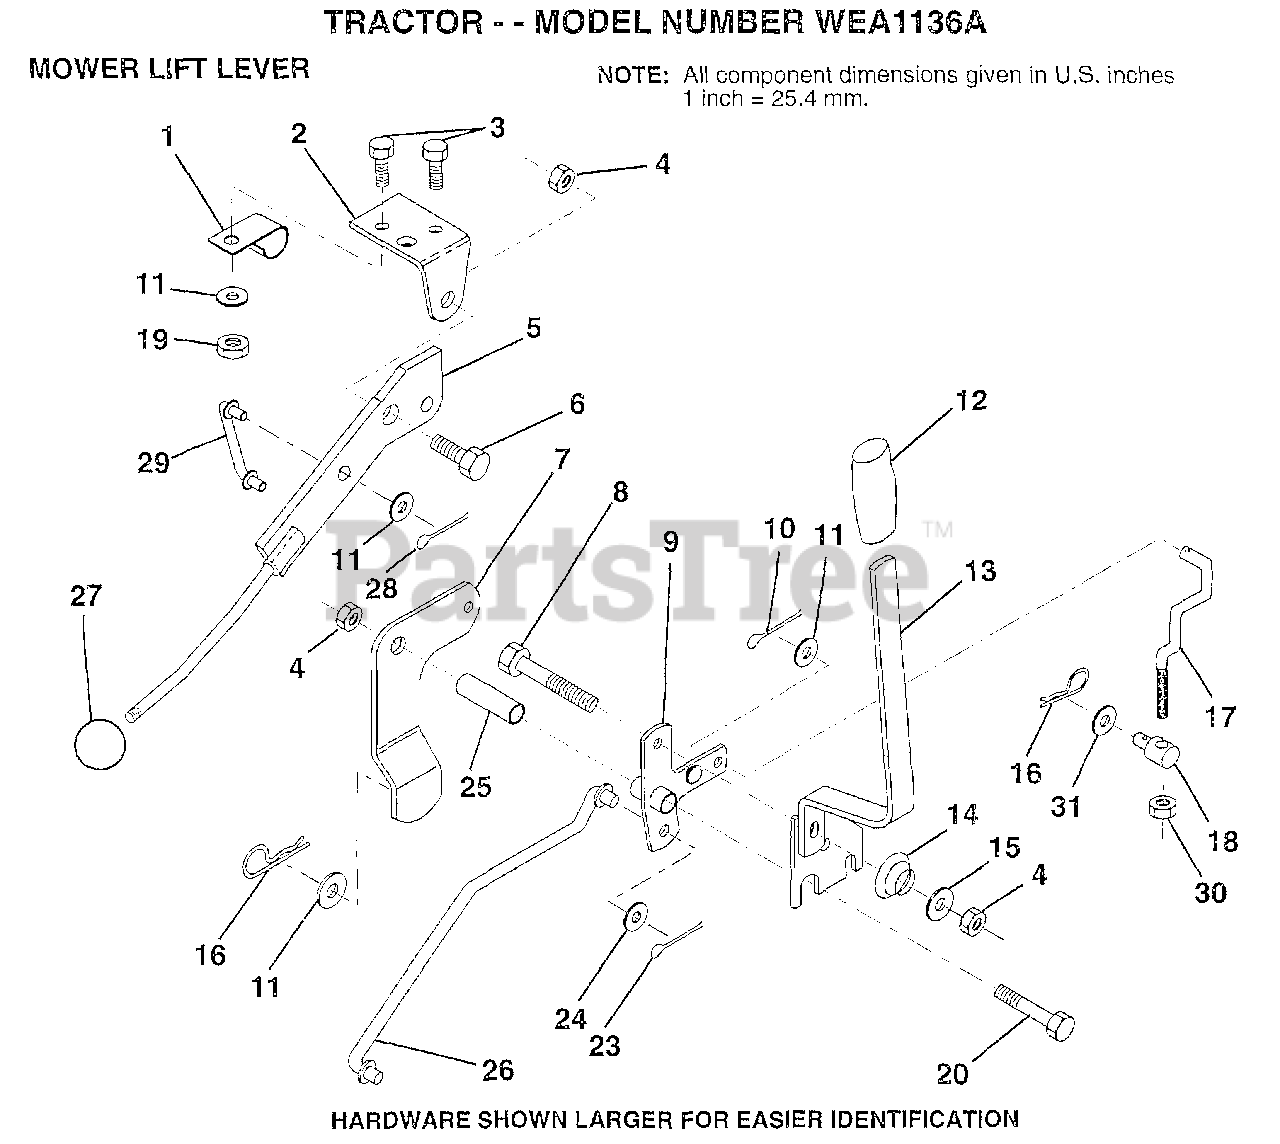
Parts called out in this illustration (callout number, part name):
1	"CLIP,INSULATOR"
2	BRKT CLUTCH
3	BOLT HXHD FIN
5	LEVER.ASM.CLUTCH
6	"BOLT, SHOULDER LT"
7	MWR CLUTCH ARM AS
8	BOLT
9	"BELLCRANK,LIFT"
10	COTTER PIN
11	WASHER
13	HANDLE.ASM.LIFT
14	SPRING COMPRESSIO
15	WASHER T
16	SPRING.RETAINER
17	"LINK,LIFT FRT"
18	TRUNION ADJ
20	BOLT
23	PIN COTTER 1/8
25	TUBE SPACER
26	ROD LIFT MOWER
27	KNOB T(3/8 HOLE)
29	CLUTCH LINK
30	NUT
31	WASHER
